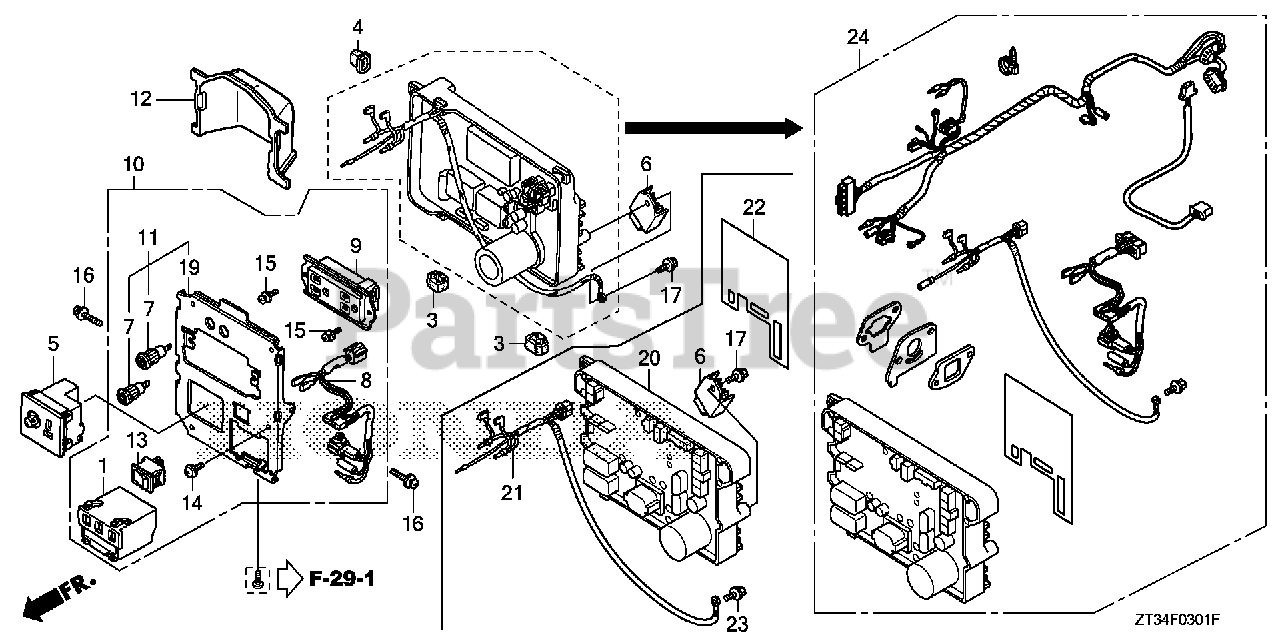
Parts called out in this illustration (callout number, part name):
1	SPARK UNIT
3	RUBBER A, INVERTER
4	RUBBER B, INVERTER
5	RECEPTACLE, D.C.
6	RECTIFIER ASSY.
7	SOCKET, COMPOSITE
8	WIRE HARNESS ASSY., CONTROL
9	RECEPTACLE ASSY. (15A/125V)
10	PANEL ASSY., CONTROL
11	PANEL, CONTROL
12	COVER, CONTROL PANEL
13	SWITCH, AUTO-THROTTLE
14	SCREW, PAN (5X12)
15	SCREW-WASHER (4X6)
16	SCREW-WASHER (5X20)
17	BOLT, FLANGE (6X12)
18	INVERTER UNIT
19	PANEL, CONTROL
24	INVERTER KIT (A)
